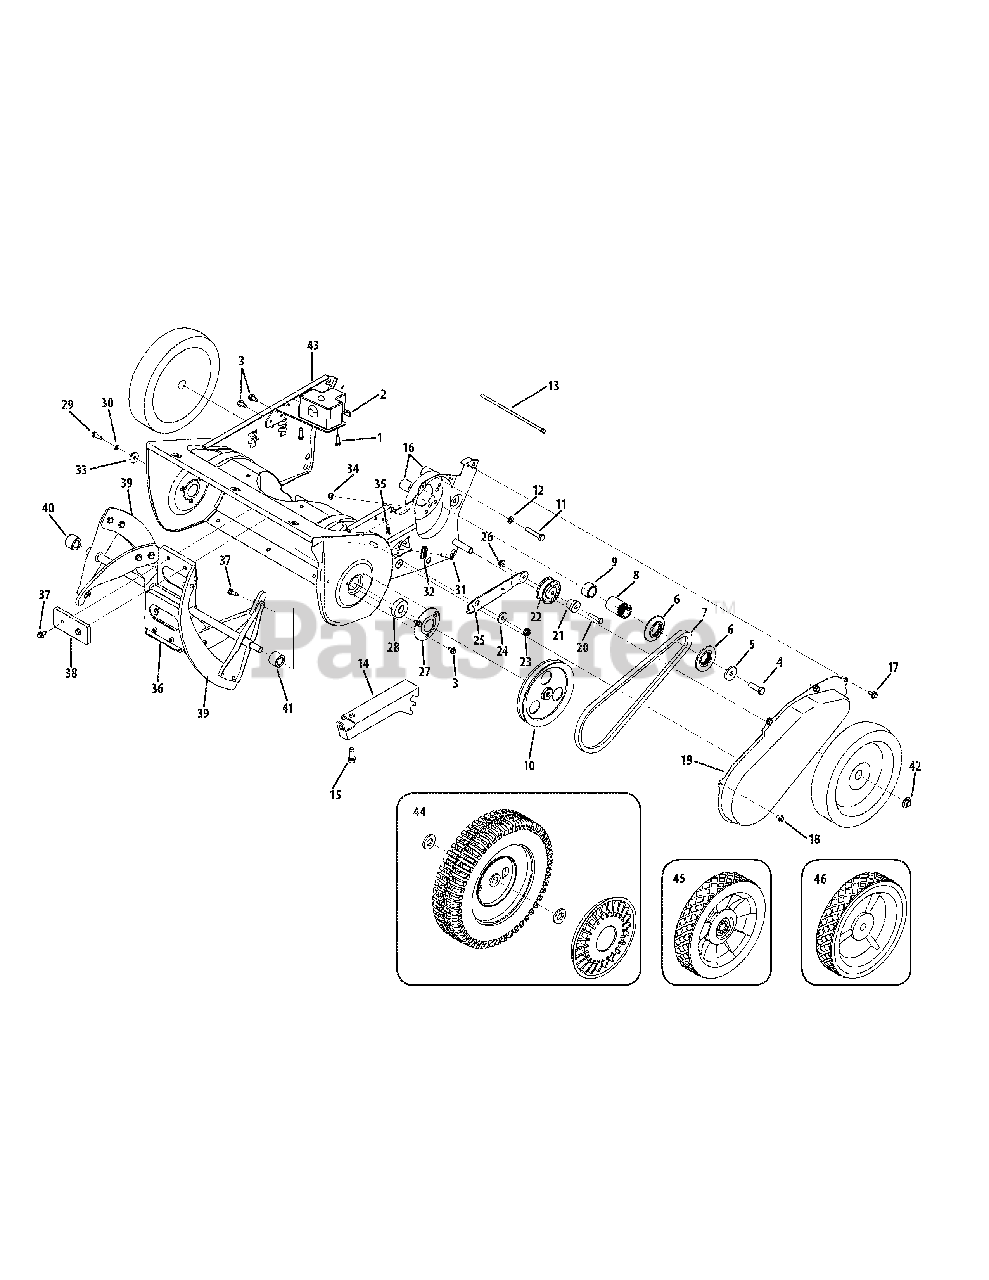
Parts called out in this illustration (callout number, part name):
1	Hi-Lo Screw #12-16 x .75
4	Hex Screw 3/8-24 x 1.25
5	Flat Washer .406 x 1.25 x .157
6	Pulley Half 4L-V x 2.30 OD
7	V-Belt
8	Spacer .875 ID x 1.185 OD
9	Spacer .88 ID x 1.18 OD x .74" Lg.
10	V-Pulley 1/2 x 6,0" OD
11	Hex Bolt 5/16-24 x 1.75
12	Lockwasher 5/16
13	Push Mount Tie
16	Spacer .875 x .320 x 1.10
17	Hex B-Tap Scr 1/4-28 x .25" Lg
18	Hex Wash HD Tapp Scr 1/4-20 x .375
20	Hex Screw 1/4-20 x 1.25 Gr. 5
21	Shoul der Spacer
22	Idler Pulley (1/4" hole)
23	Flange Locknut 5/16-18 Gr. F, Nylon
24	Shoulder Spacer .25 Thk.
26	Flange Locknut 1/4-20 Gr. F, Nylon
28	Ball Bearing .625 x 37 x 12.63
29	Thd Forming Scr. 1/4-20 x .75 Lg.
30	L-Wash 1/4 ID
31	Hex Shld.Scr.1/4-28 x .375
32	Cable Guide Roller
33	Flat Washer .25 ID x .93 OD x .125
34	Hex Ins Jam L-Nut 1/4-28
35	Extension Spring .33 OD x 1.12 Lg.
37	Hex B-Tap Scr 1/4-28 x .25" Lg
38	Rubber Paddle
39	Rubber Spiral-Crescent
40	Auger Spacer RH
41	Auger Spacer LH
42	Push Cap x 1/2" Rod
44	Wheel, 9 x 2.125 dia. Lug
44	Hub Cap
44	Flat Washer .510 ID x 1.0 OD x .125
45	Wheel, 7.0 x 1.5
46	Wheel, 7.0 x 1.61
